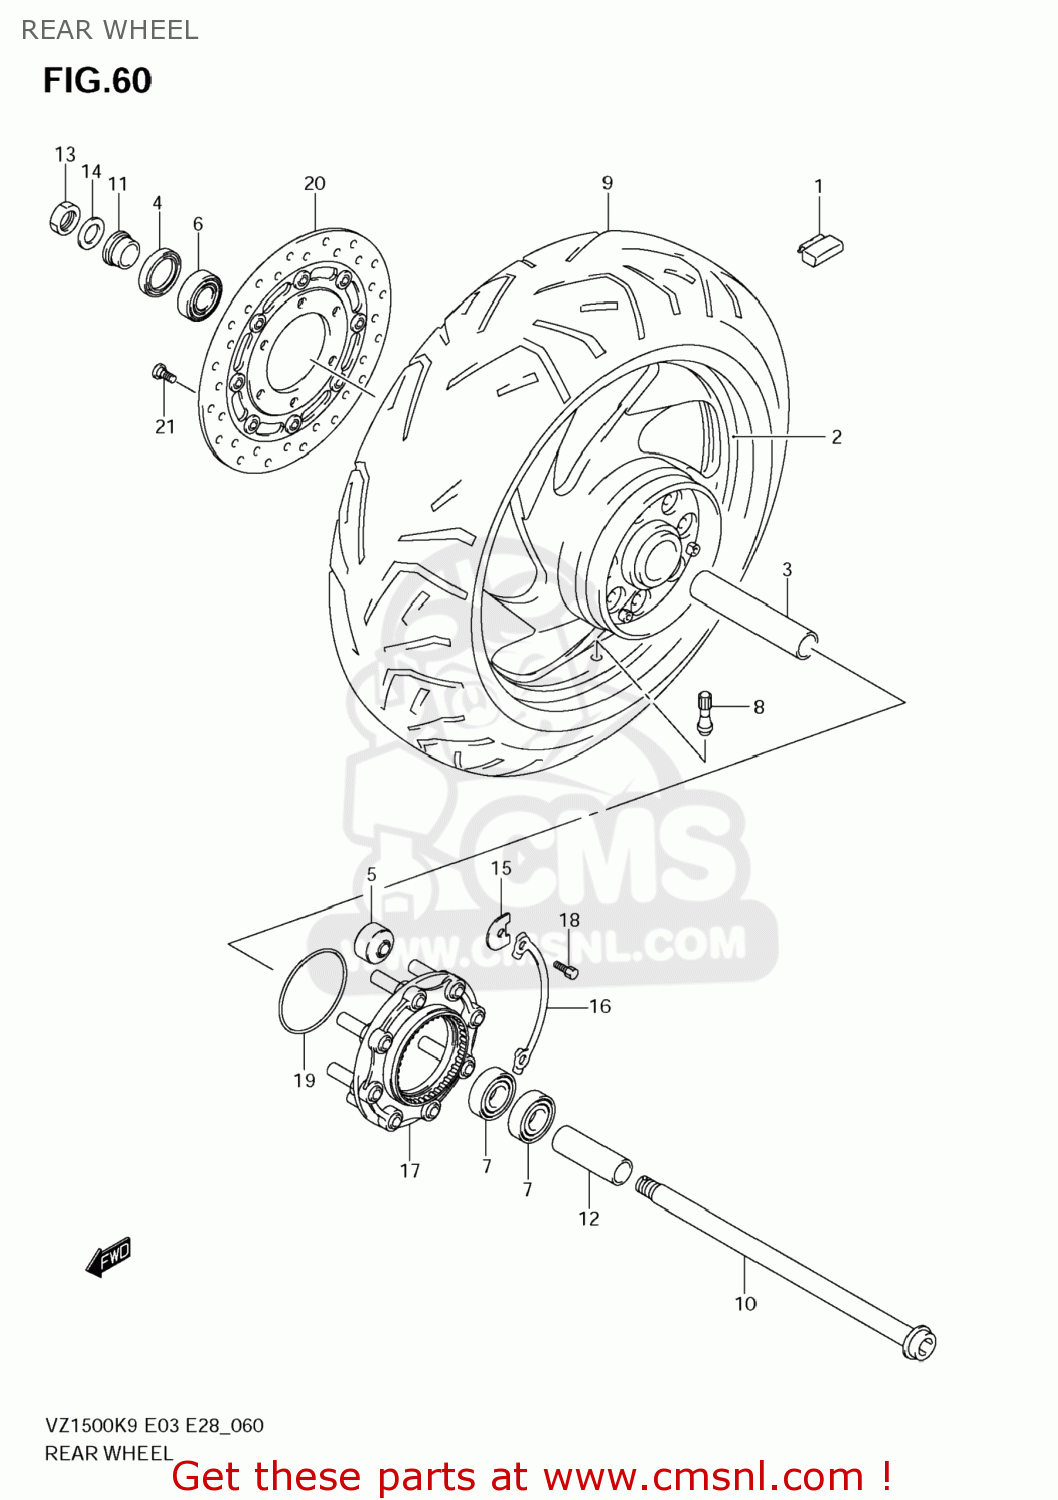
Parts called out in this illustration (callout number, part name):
1	BALANCER,WHEEL(10G)
2	WHEEL,RR(17M/CXMT6.00)
3	SPACER,RR WHEEL BEARING
4	SEAL,OIL(32X52X7)
5	BUSH
6	BEARING(25X52X15)
7	BEARING
8	VALVE ASSY,WHEEL RIM(TR412)
9	TIRE,RR
10	AXLE,RR
11	SPACER,RR AXLE,R
12	SPACER,RR AXLE,L
13	NUT
14	WASHER(22X35X2)
15	WASHER,THRUST
16	WASHER,RR HUB DRIVEN JOINT
17	JOINT ASSY,RR HUB DRIVEN
18	BOLT(6X16)
19	O RING(D:2.4,ID:79.8)
20	DISC,RR BRAKE
21	BOLT(8X21)
